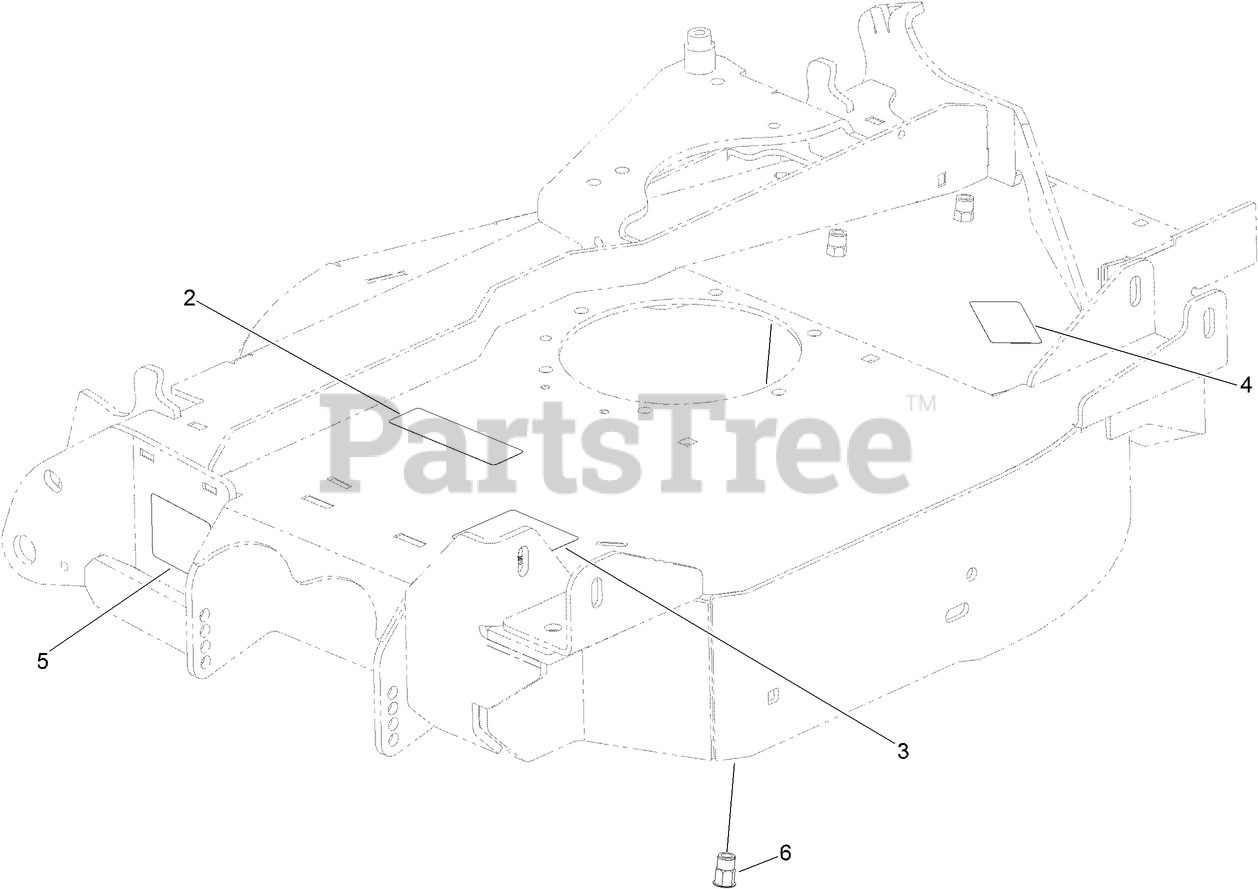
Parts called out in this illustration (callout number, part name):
2	DECAL-COVER, MISSING
3	DECAL-DANGER, THROWN OBJECT
4	DECAL-TORQUE, BOLT
5	DECAL-WARNING, PINCH POIN
6	NUT-CLINCH,HEX
